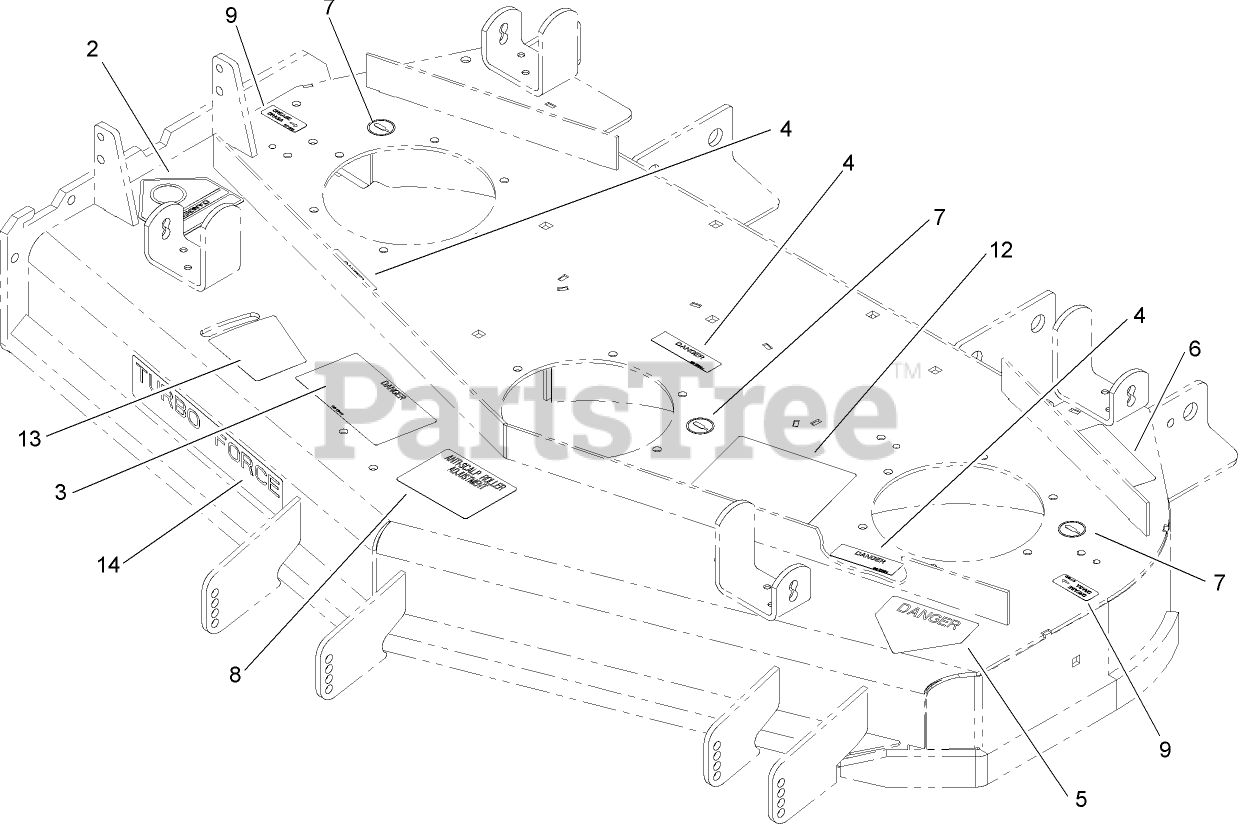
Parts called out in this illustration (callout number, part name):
2	DECAL-DANGER
3	DECAL-DANGER, THROWN OBJECT
4	DECAL-COVER, MISSING
5	DECAL-DANGER
6	DECAL-TORQUE
7	DECAL-GREASE
8	DECAL-SCALP, ANTI
9	Decal-Grease
12	DECAL-AID, SERVICE
13	DECAL-ADJUSTMENT, BAFFLE
